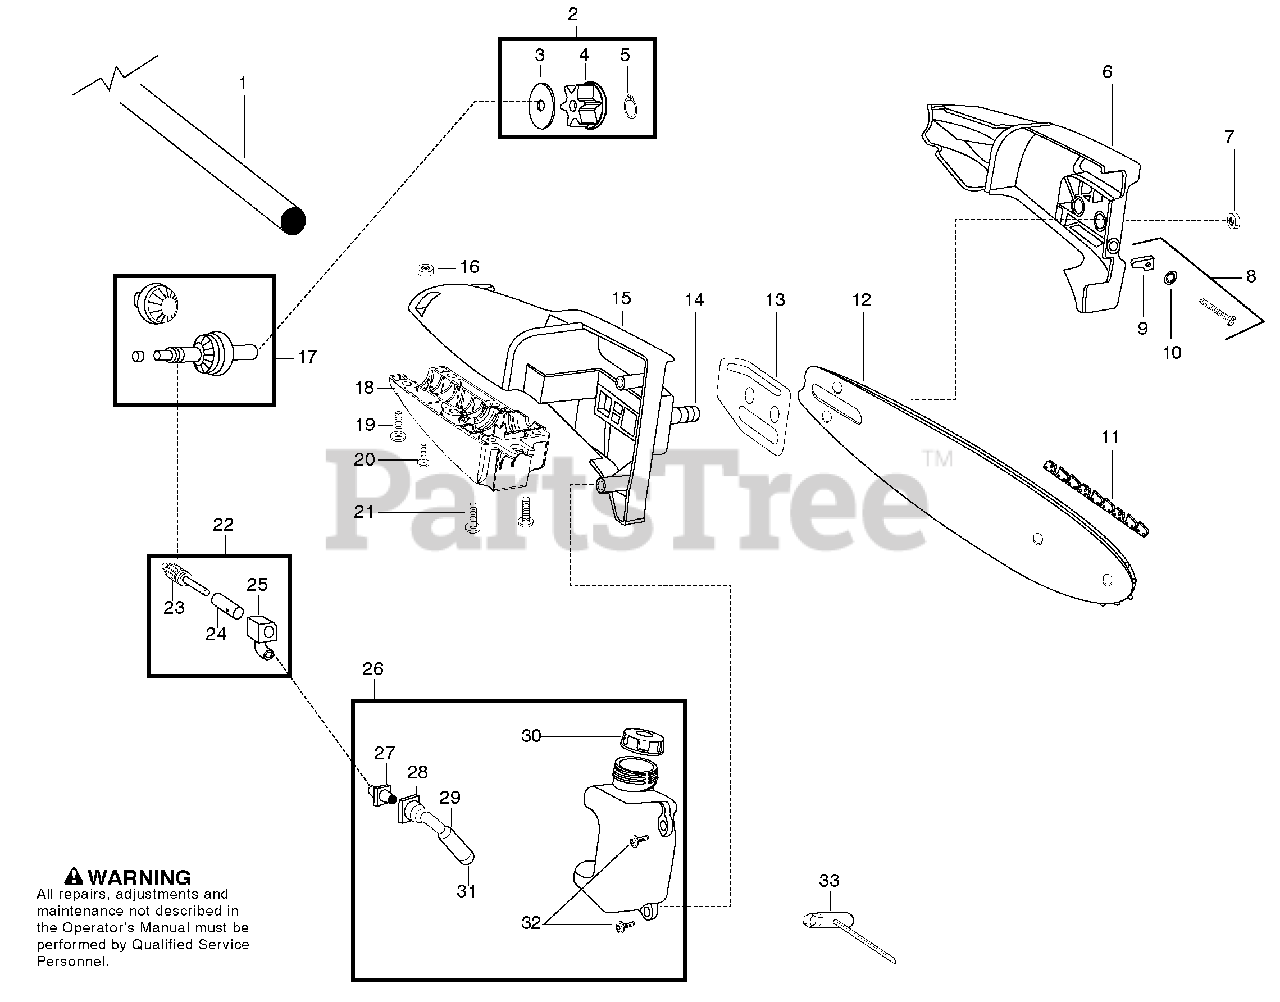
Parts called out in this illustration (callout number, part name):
1	Assy. - Driveshaft
2	Kit - Sprocket Assy.
4	Sprocket
5	Retainer - Sprocket
6	Assy - Bar Clamp
7	Nut - Bar Mounting
8	Kit - Bar Adjust
9	Pin - Bar Adjust
10	Retainer - Bar Adjust
11	Accy - 8" Chain
12	Bar - 8"
13	Plate - Bar Pad
14	Bolt - Bar
15	Housing - Upper
17	Kit - Gear Assy.
18	Housing - LowerScrew
20	Screw - Alignment
22	Kit - Oil Assy
23	Assy. - Gear Plunger
25	Block - Oil
26	Assy - Oil Tank
27	Fitting - Oil Line
28	Intake - Oil Line
29	Filter - Oil
30	Cap - Oil
31	Plug - Oil Filter
33	Wrench - Bar
